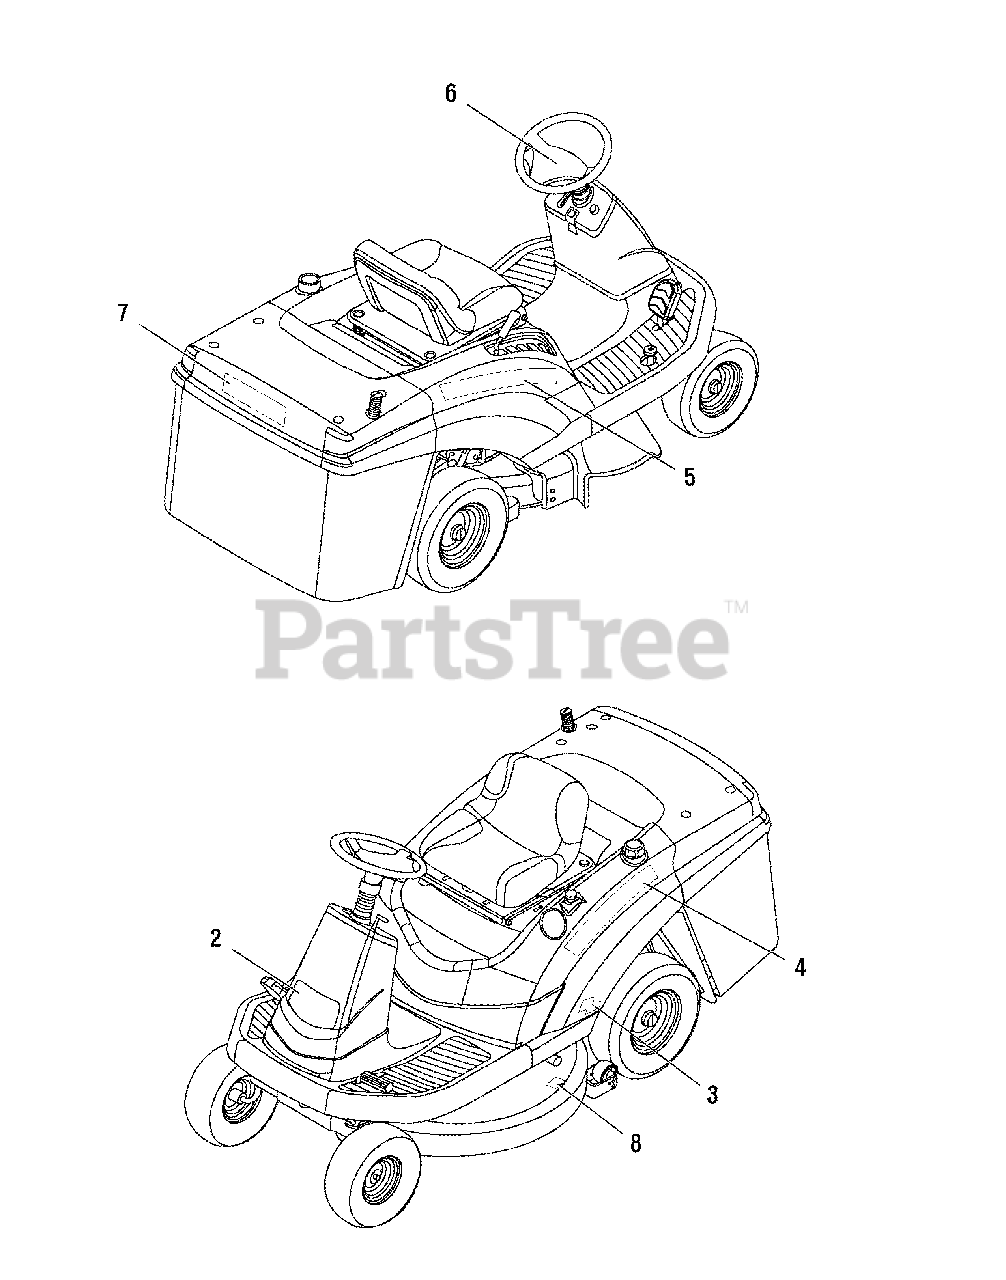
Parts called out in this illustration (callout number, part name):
2	DECAL, Nose, Snapper
3	DECAL, Snapper 15.5 HP
3	DECAL, Snapper 17.5 HP
4	DECAL, Stripe, LH
5	DECAL, Stripe, RH
6	DECAL, Steering Wheel Insert
7	DECAL, Bagger Cover
8	DECAL, Deck Width
